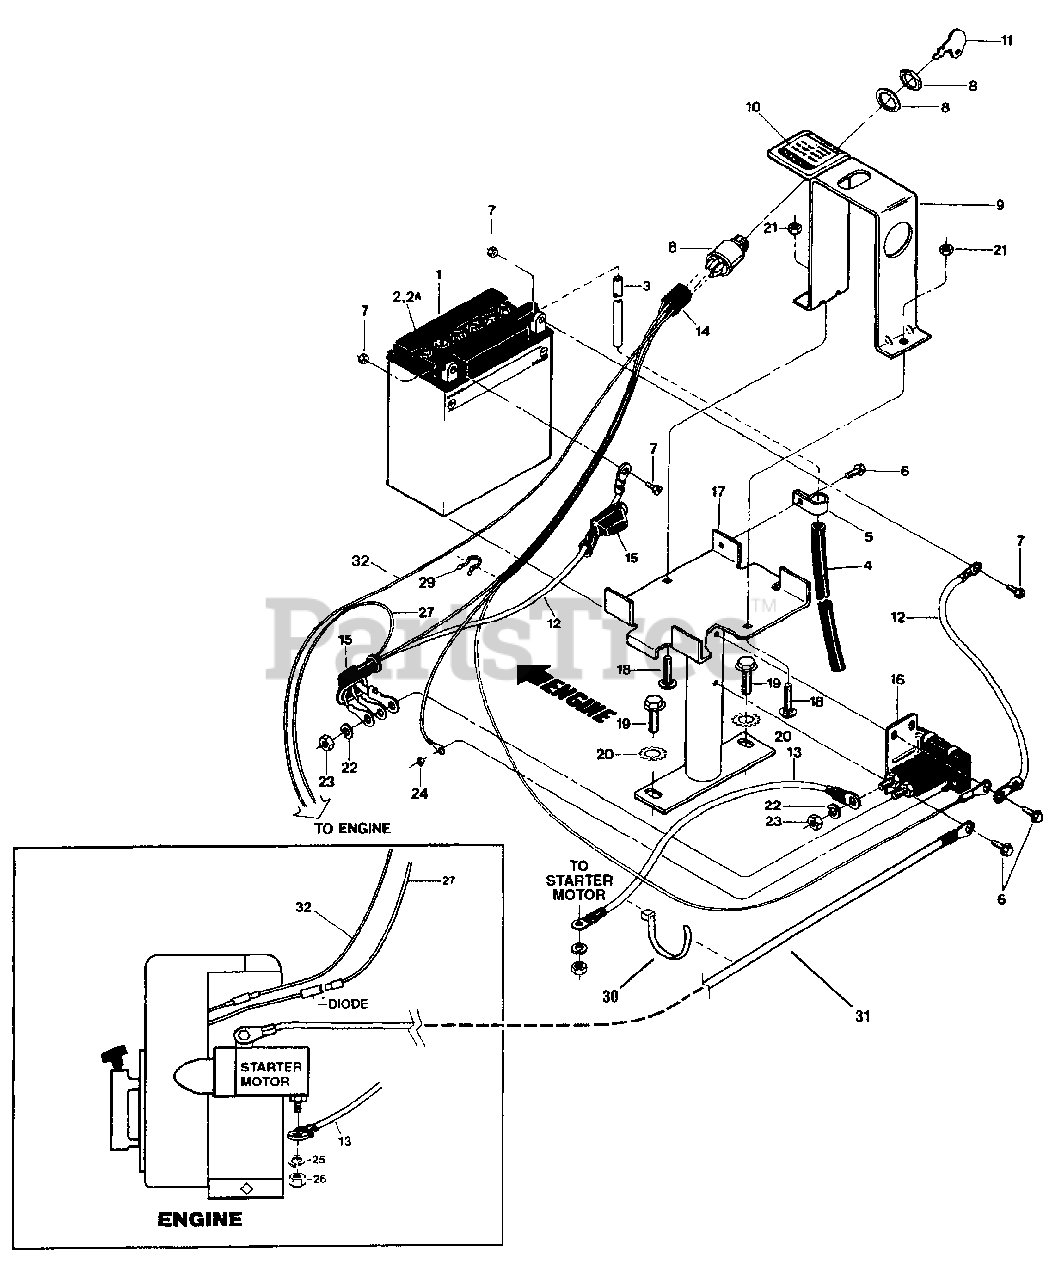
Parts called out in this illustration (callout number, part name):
1	Battery, 12 Volt, 9 Amp
2	Battery Cap (yellow)
2A	Battery Cap (white)
3	Vent Tube
4	Shield, Vent Tube (hard plastic)
5	Clamp
6	Hex Flange Screw, Self-Threading, 1/4-20 x 1/2"
7	Battery Hardware Kit -
8	Ignition Switch
9	Battery Hold-Down Clamp/Switch Mounting Plate Assy.
10	Decal, Ignition Switch
11	Ignition Key (pair)
12	Battery Cable
13	Cable (solenoid to starter motor)
14	Wire Harness Assy. (Available as complete assembly only);
15	Boot, Insulating
16	Solenoid
17	Battery Bracket
18	Round Hd. Screw, Square Neck, 1/4-20 x 1-1/4
19	Hex Flange Screw, 5/16-18 x 1'
20	Lockwasher, External Tooth 2
21	Hex Locknut, 1/4-20 2
22	Lockwasher, 5/16 2
23	Hex Nut, 5/16-24 2
24	Hex Locknut, #10-32
27	Recharge Wire Assembly
29	Plastic Wire Tie
30	Plastic Wire Tie
31	Cable (ground wire to starter motor bracket)
32	Ground Wire Assy. (shut off)
